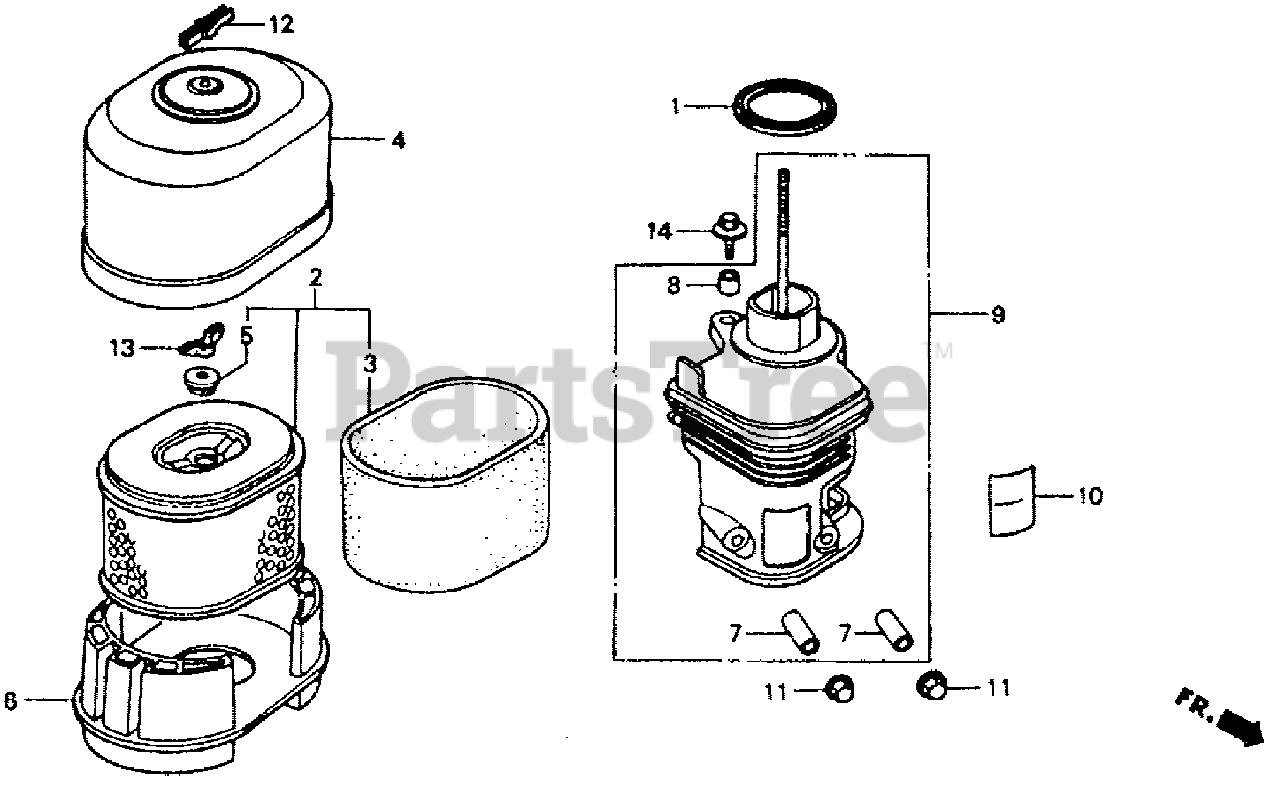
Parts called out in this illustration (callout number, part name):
1	GASKET, ELBOW
2	ELEMENT, AIR CLEANER (DUAL)
3	FILTER (OUTER)
4	COVER, AIR CLEANER (DUAL)
5	GROMMET, AIR CLEANER
6	NOSE, MUFFLER
7	COLLAR, AIR CLEANER
8	COLLAR B, AIR CLEANER
9	ELBOW, AIR CLEANER
10	MARK, CHOKE (EXTERNAL)
11	NUT, CAP (6MM)
12	WINGNUT, AIR CLEANER COVER
13	WINGNUT, TOOL BOX SETTING
14	BOLT-WASHER (6X20)
